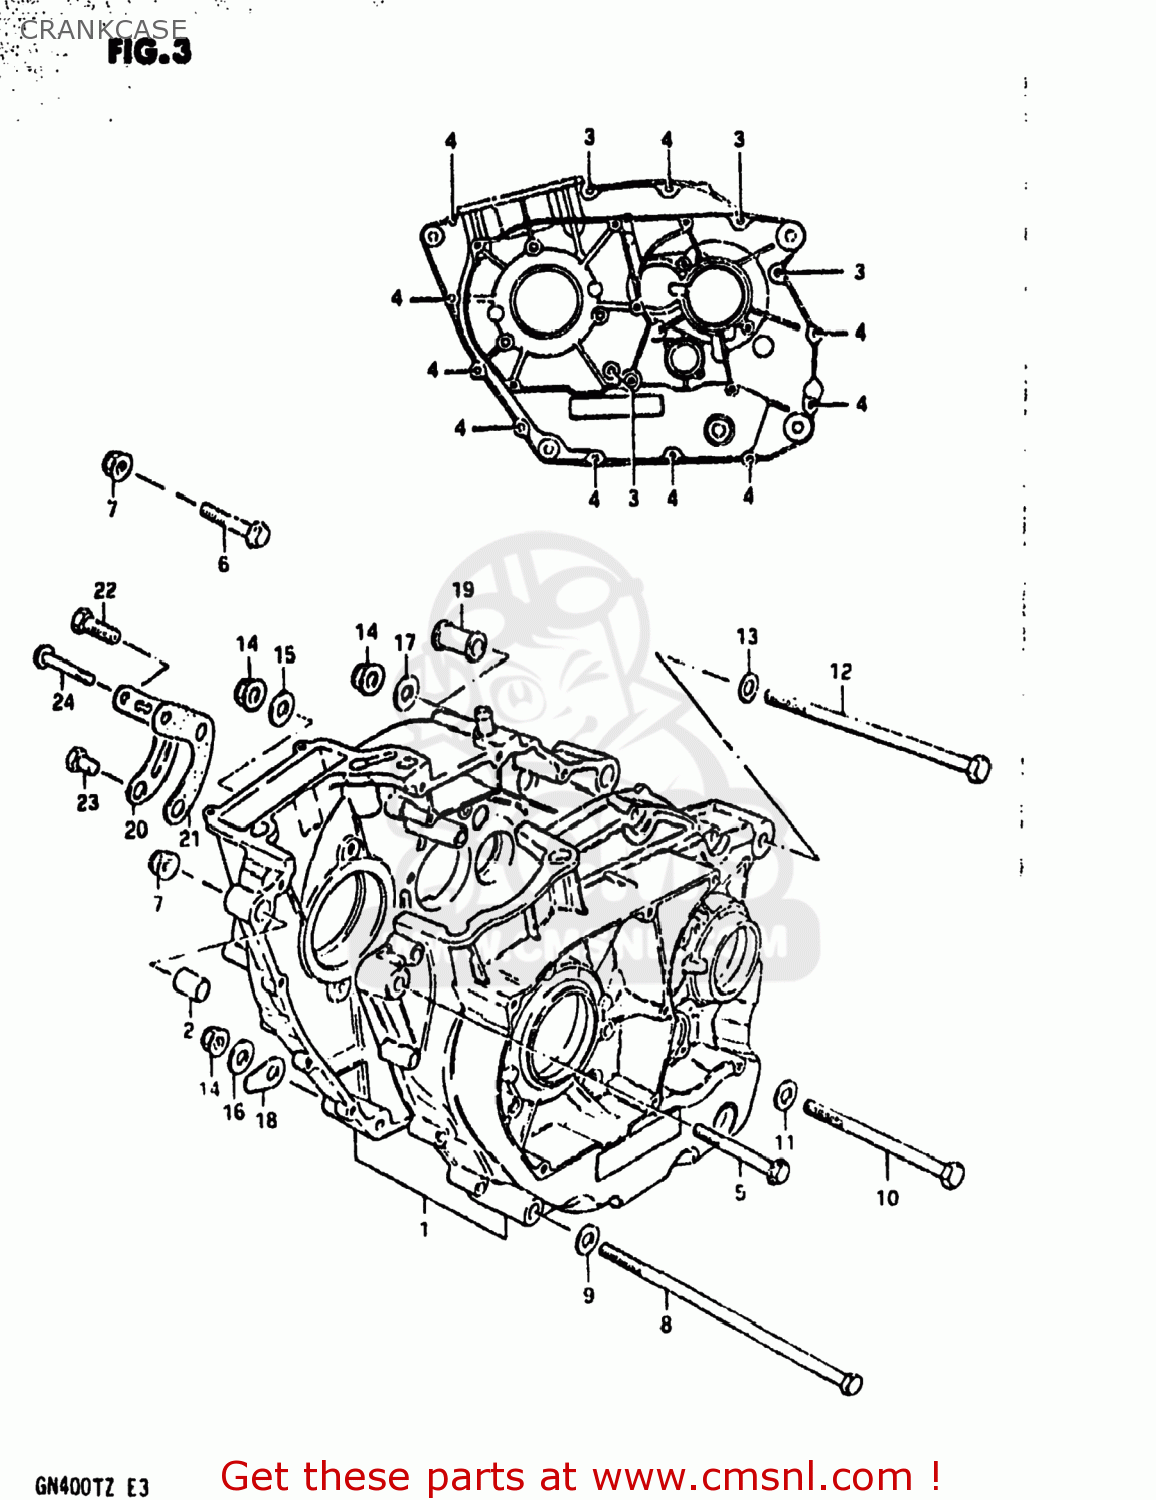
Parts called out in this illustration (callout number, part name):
1	CRANKCASE SET
2	PIN
3	SCREW
4	SCREW (6X35)
5	BOLT (8X70)
6	BOLT
7	NUT
8	BOLT 10X155
9	WASHER
10	BOLT 10X115
11	WASHER(10.5X20X3.2)
12	BOLT(10X190)
13	WASHER
14	NUT
15	WASHER
16	WASHER(10.5X20X3.2)
17	WASHER
18	WASHER
19	SPACER
20	CAP,OIL GALLERY
21	GASKET,OIL GALLERY (MCA)
22	BOLT,UNION
23	PLUG
24	BOLT
